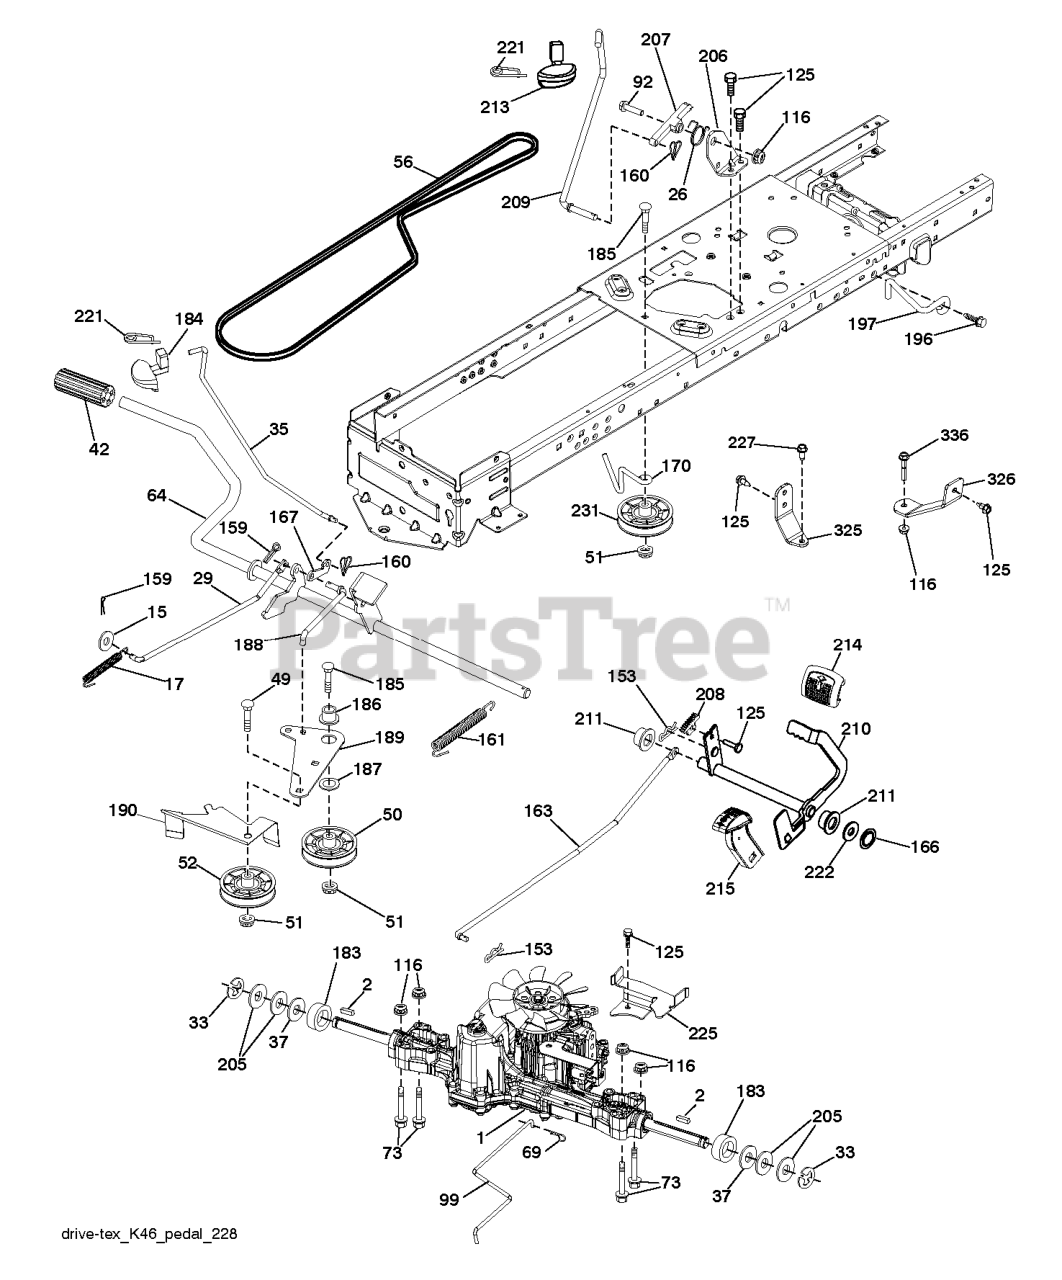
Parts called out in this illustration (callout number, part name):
2	SQUARE KEY
15	WASHER
17	SPRING.BRAKE.K46.GREEN
26	SPRING.RETURN.CRUISE
29	ROD.BRAKE.K46
35	ROD ROD.PARKINGBRAKE.GT.HUSQ/P
37	WASHER.HARDENED
42	PEDAL COVER T
50	IDLER.FLAT.910.OFFSET
51	NUT LOCK FLG 3/8-16 UNC
52	IDLER.V-GROOVE.910.OFFSET
56	V-BELT.MOWER.92.40.42/K46
64	SHAFT.ASM.PEDAL.BRK.CNTR
69	HAIRPIN.SOFT.ZINC.059X1.125
73	BOLT
92	BOLT
99	ARM.PIVOTING.TCRD.GEN2.5.BAGGE
116	NUT LOCK HEX FLANGE 5/16-18
125	SCREW
153	RETAINER M
159	COTTER PIN
160	RETAINER CLIP
161	SPRING, RETURN LT
163	ROD.CONTROL.K57R.K46
166	NUT.PUSH.625
167	LATCH.BRAKE.SPRING
170	KEEPER.CENTER SPAN.1.688
183	SPACER AXLE
184	HANDLE.PARKING.BRAKE.H (BLK)
186	SPACER.RETAINER
187	WASHER 12/32X2X10GA
188	LINK.CLUTCH.GROUND DRIVE.LONG
189	BELLCRANK.GROUND.DRIVE.TEX.
190	KEEPER.BELLCRANK.DRIVE
196	SCREW 3/8-16X1
197	BRKT.42.FCS.CLUTCH.ANTIROTATIO
206	BRACKET.MOUNT.CRUISE.LATCH
207	LATCH.CONTROL.CRUISE.TEX
208	GEAR.SECTOR.CONTROL.CR
209	ROD ROD.CRUISECONTROL.GT.HUSQ/
210	ROCKER.ASM.PEDAL.CONTR
211	BEARING.NYLON
213	KNOB.CONTROL.CRUSIE.HU
214	PEDAL.FORWARD.PAD.TEX
215	PEDAL.COVER.REVERSE.CRD.X428BK
221	RETAINER.SPRING.CLIP.H
222	WASHER 21/32 X 1-1/4 X 10 GA.
225	KEEPER.BELT.TRANSAXLE.K46
227	SCREW.THDROL.5/16-18X3/4.TTY
231	IDLER.V-GROOVE.1.688.OFFSET
325	TORQUE.STRAP.K46.LT.LH
326	BRCKT.PNT.TRQ.STP.46.18TIRE.RH
336	BOLT.5/16-18X1-3/4.FLANGED.HEX
